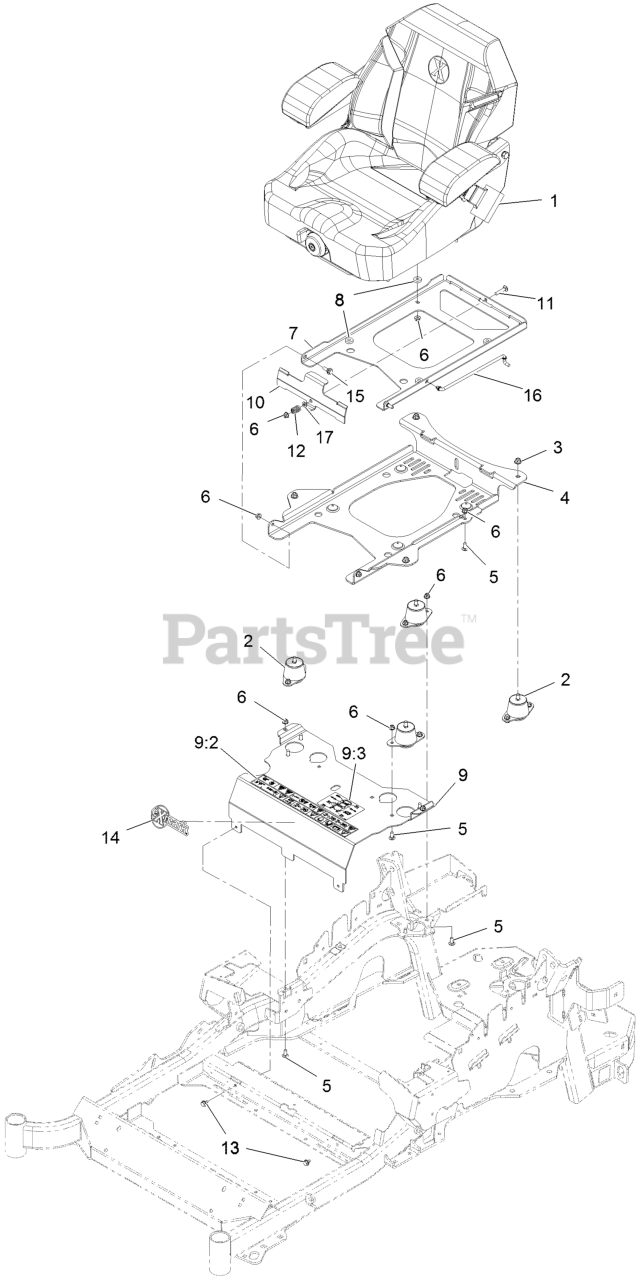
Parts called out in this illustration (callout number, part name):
1	KIT-SUSPENSION SEAT
2	ISOLATOR-SEAT
3	NUT-HF, NI
4	PLATE-TILT, SEAT SUPPORT
5	SCREW-CARR
6	NUT-HF, NI
7	PLATE-FRAME, SEAT
9	MOUNT-SEAT
9:2	DECAL-CONSOLE
9:3	DECAL-SERVICE AID
10	PLATE-LATCH, SEAT
11	BOLT-CARR
12	SPRING-COMPRESSION
15	SCREW-SHOULDER
16	ROD-PROP
17	WASHER-PLAIN
